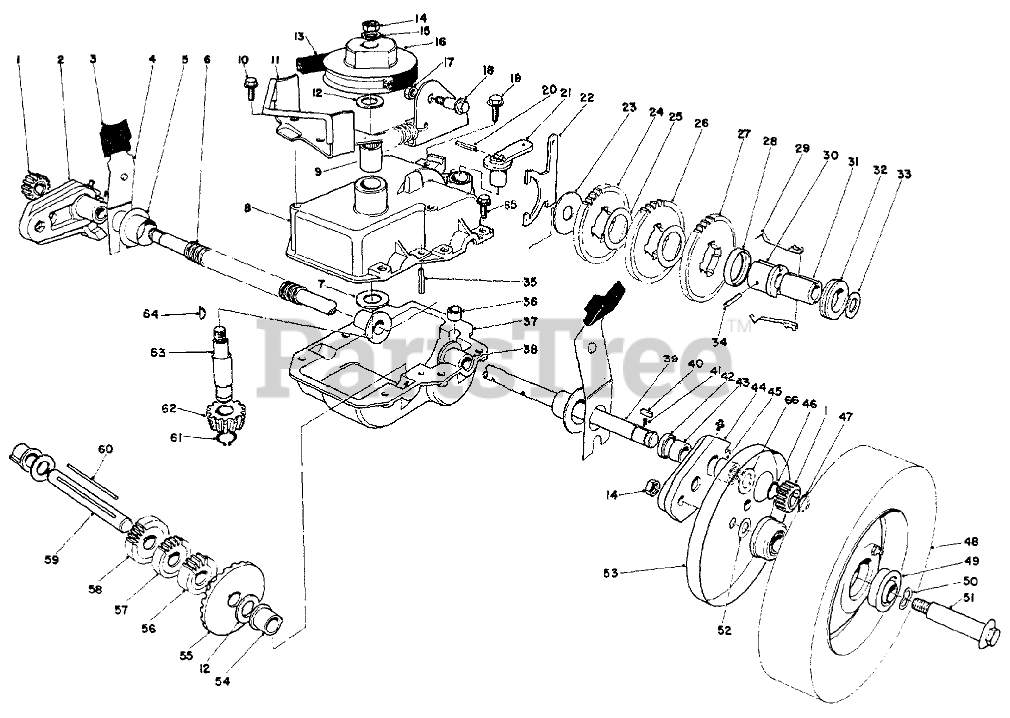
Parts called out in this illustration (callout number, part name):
1	GEAR-PINION
2	Pivot Arm R.H. (Incl. Ref. #42, 43 & 45)
3	KNOB-ARM
4	Spring Arm
5	CAP-END
6	CONDUIT-CONVOLUTED, SPLIT
7	Thrust Washer
8	Case-Upper
9	Bearing
10	Screw
11	Belt Guide Bracket
12	WASHER-THRUST
13	V-BELT
14	Nut
15	WASHER-FLAT
16	PULLEY
17	NUT-LOCK
18	Shoulder Bolt
19	SCREW-HWHTF
20	PIN-COIL
21	LEVER-SHIFT
22	Shift Yoke
23	WASHER
24	GEAR-38T
25	WASHER
26	Gear-40 Tooth
27	GEAR-42T
28	KEY RETAINER
29	Key
30	Body-Sleeve
31	SLEEVE
32	COLLAR-SHIFT
33	WASHER-PLAIN
34	PIN-SPRING
35	ROLL PIN 3/16 X 1 IN
36	BUSHING-YOKE
37	LOWER GEAR CASE CAST
38	Bushing
39	Output Shaft
40	KEY RECTANGULAR
41	SPRING-COMPRESSION
42	Seal
43	Bushing
44	Pivot Arm L.H. (Incl. Ref. #42, 43 & 45)
45	Needle Baring
46	RING-EXT GRIP
47	RING-RETAINING
48	Wheel & Tire Assembly (Incl. Ref, #49)
49	BEARING-BALL
50	SPRING WASHER
51	WHEEL BOLT
52	WASHER
53	Cover-Wheel
54	Botching Shaft
55	BEVEL GEAR
56	14 T GEAR
57	16 T GEAR
58	GEAR-18T
59	Sort Shaft
60	Key Square
61	RING-RETAINING
62	PINION-BEVEL
63	INPUT SHAFT
64	KEY-WOODRUFF
65	SCREW-HWH, THREAD ROLL
66	Washer
